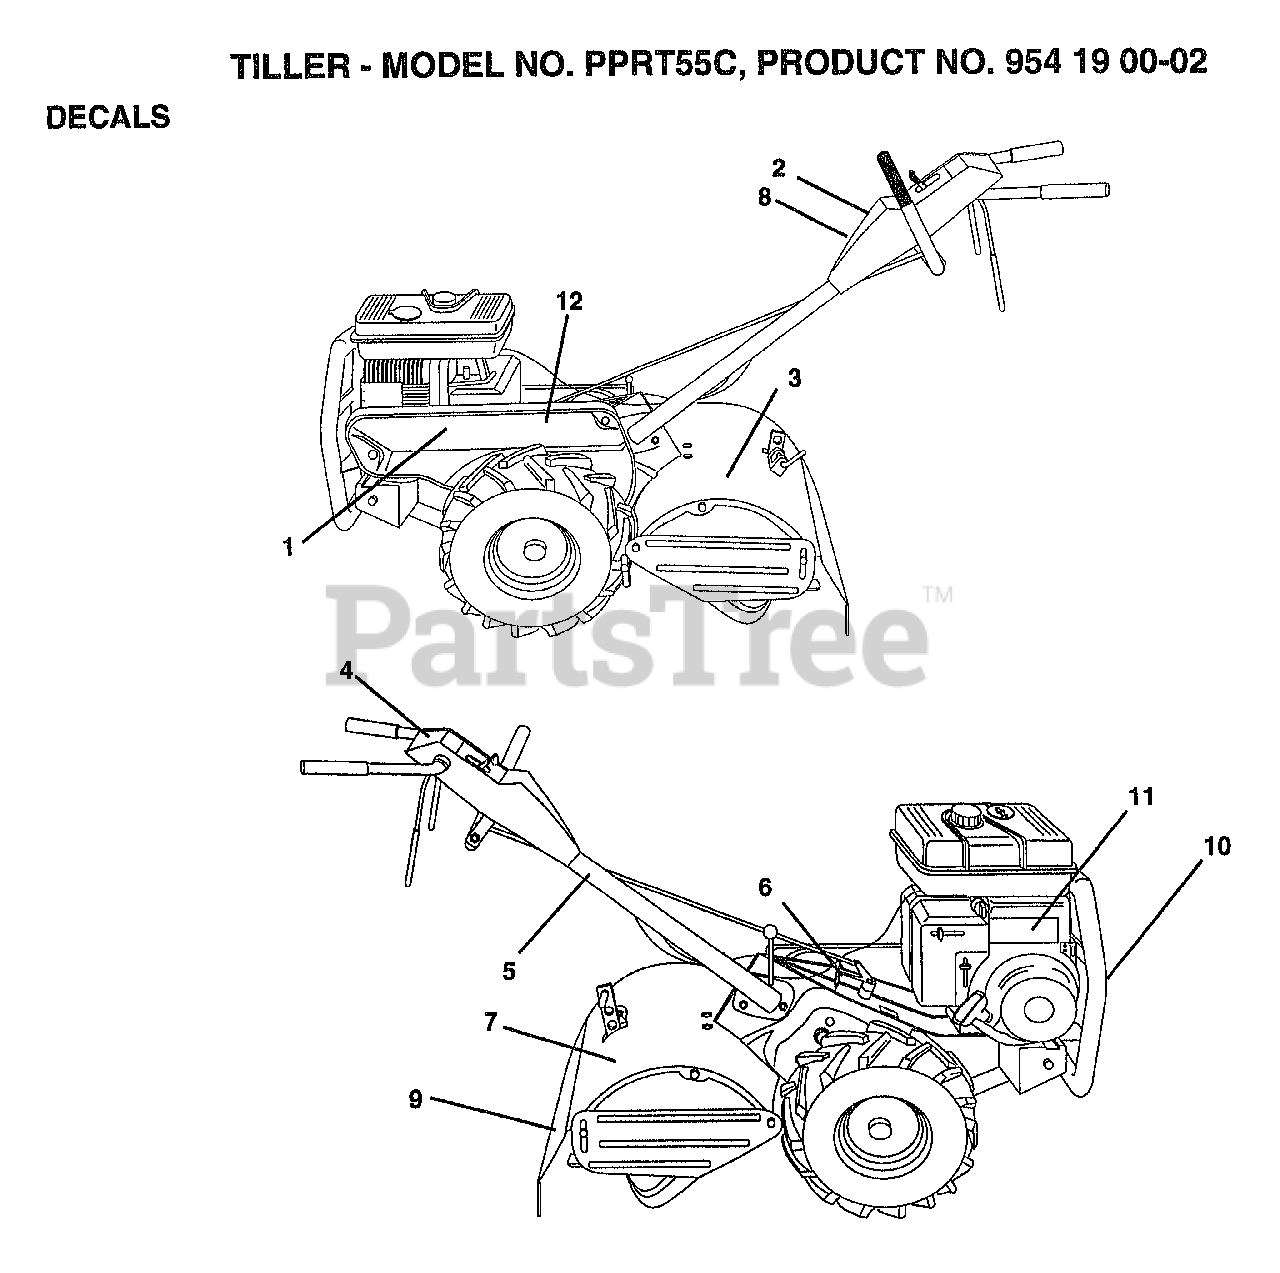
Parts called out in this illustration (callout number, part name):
1	DECAL, LOGO
2	DECAL.FENDER.BELT.GUARD
3	DECAL, LOGO
4	DECAL.INSTRUCTION
5	DECAL TI
6	DECAL CRT
7	DECAL.CAUTION
8	DECAL.CTRL.PANEL.5.5HP
10	DECAL, BUMPER/GRILLE
11	DECAL, ENGINE PRED.
12	RETAINER-SPRING
